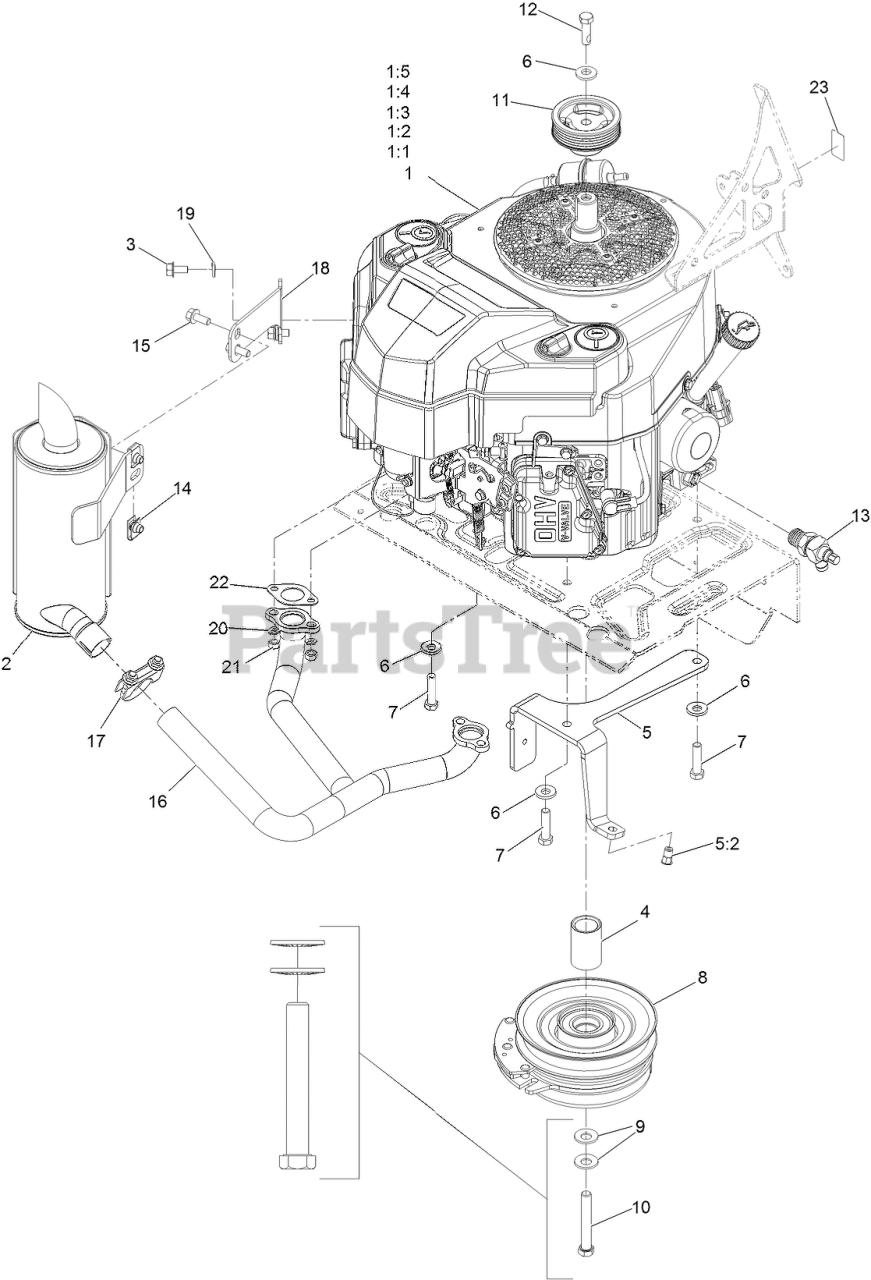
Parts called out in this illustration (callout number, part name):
1:1	Kawasaki 49065-7007 Engine Oil Filter
1:2	Kawasaki 49019-0031 Fuel Filter
1:4	Kawasaki 11013-7046 Foam Pre-Filter
1:5	Kawasaki 11013-0752 Air Filter
2	Muffler-Vertical Ka
3	SCREW-HHF
4	Spacer-Clutch
5	ASM-Clutch Anchor W/Insert
5:2	Nut-Clinch,Hex
6	WASHER-BELLEVILLE
7	SCREW-HH
8	Clutch 105
9	WASHER-SPRING
10	SCREW-HH W/LOCTITE
11	PULLEY, CRANK
12	Screw-HH, Patch
13	Drain-Oil Valve
15	SCREW-HHF
16	Manifold-Vertical Ka Exh
17	CLAMP-MUFFLER
18	Bracket-Muffler Vertical
19	WASHER-LOCK
20	WASHER-LOCK
22	GASKET-EXHAUST
23	Decal-10W-50 Oil
